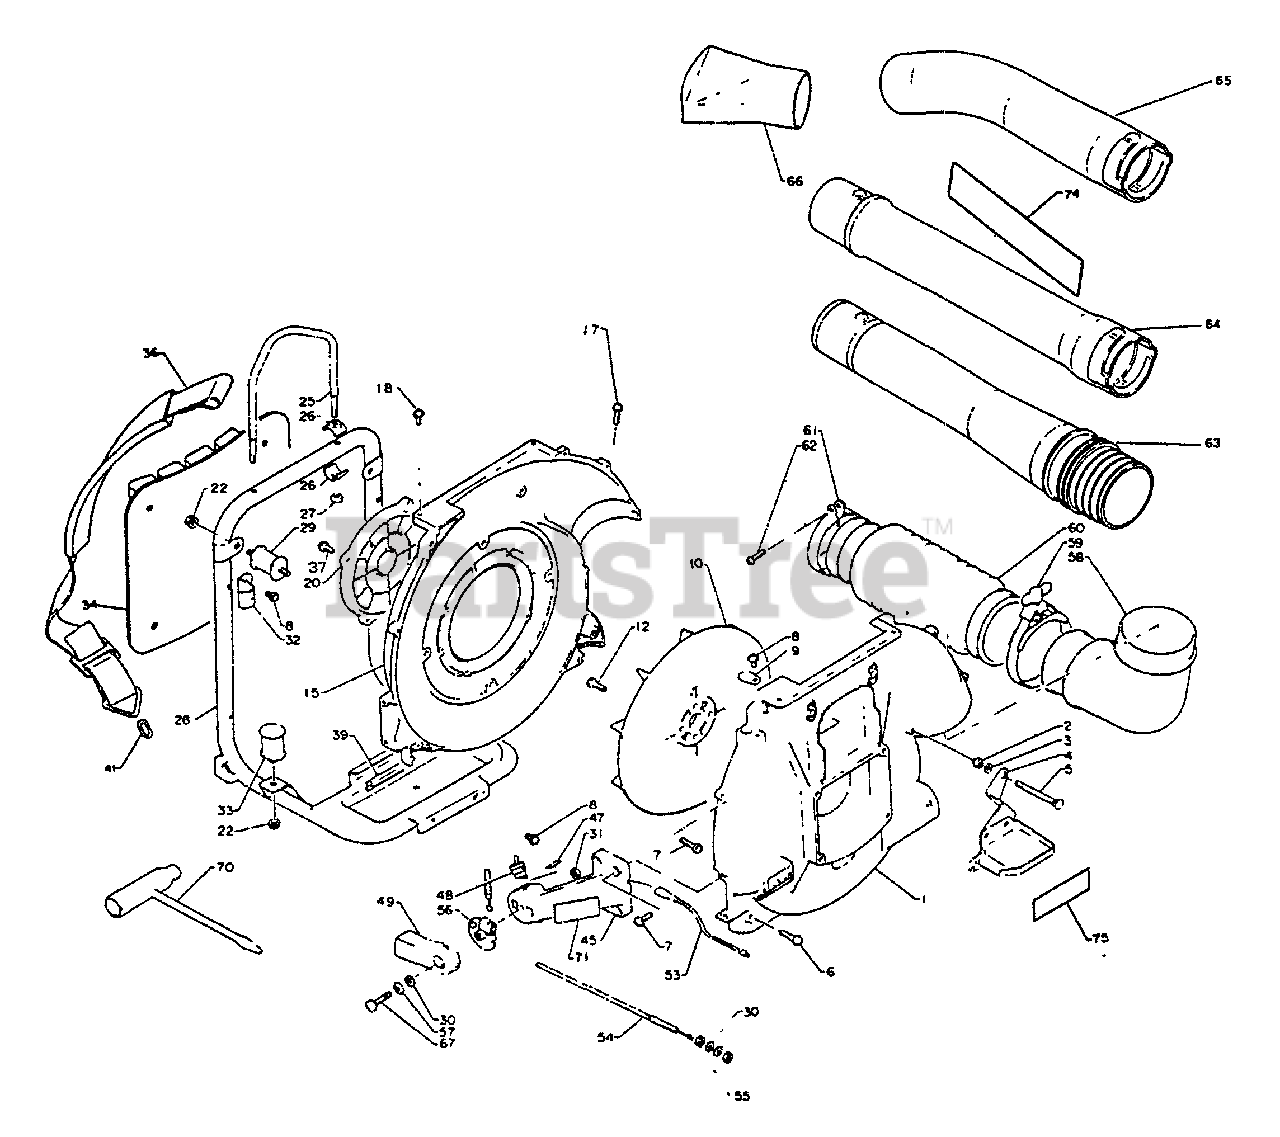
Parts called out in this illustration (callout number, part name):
1	COVER, FAN - OUTER
2	NUT - 5 -- CAP
3	WASHER, FLAT 5.5×10×0.8
4	BRACKET, MUFFLER COVER
6	SCREW 5×25
7	SCREW 5×20
8	SCREW 5×10
15	COVER, FAN - INNER -- ORANGE
17	SCREW 6×20
18	SCREW 6×15
20	SHIELD, DEBRIS
22	NUT, FLANGE M6
27	LOCKNUT - 6
28	FRAME, BACKPACK
31	NUT, HEX M6
32	BRACKET, CUSHION
34	CUSHION, BACKPACK
36	BACKPACK STRAP ASSY
41	RING, HARNESS
45	MOUNT, THROTTLE LEVER
47	LABEL, ON-OFF
48	IGNITION SWITCH ASSY
49	CONTROL, THROTTLE
54	CABLE, THROTTLE
60	TUBE, FLEXIBLE
61	CLAMP KIT
62	SCREW 5×25
63	TUBE, BLOWER - SWIVEL
64	BLOWER TUBE KIT - STRAIGHT
65	TUBE, BLOWER - CURVED
66	NOZZLE - FAN HEAD
67	SCREW 6×25
70	T-WRENCH 10×19 MM
71	LABEL - CAUTION
74	LABEL - ECHO
75	LABEL - NOISE
